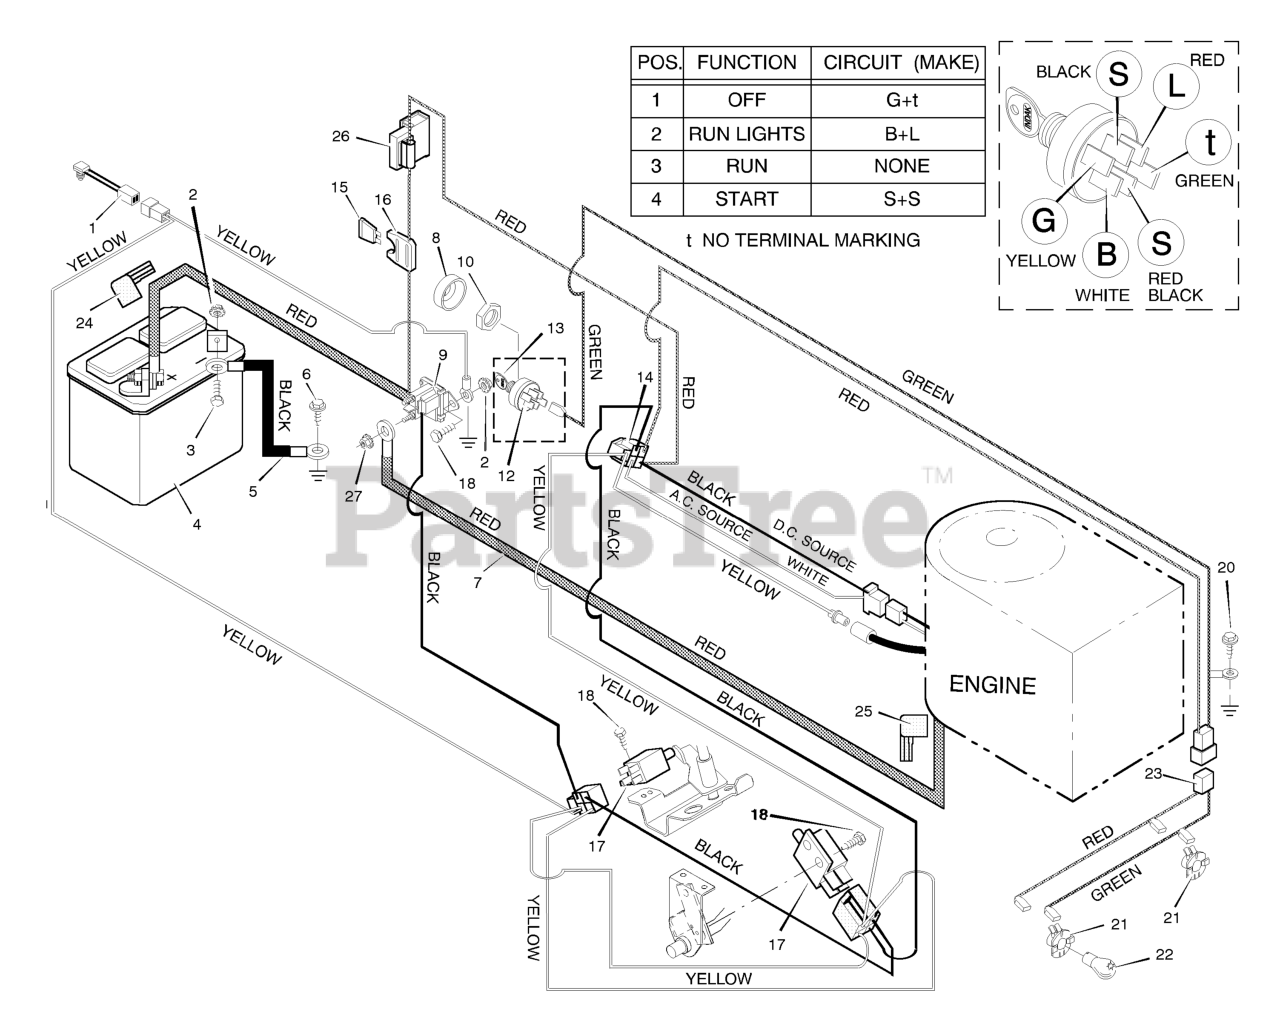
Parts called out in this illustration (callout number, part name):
1	Switch, Seat Sensor
2	Locknut
3	Bolt, Hex
4	Battery
5	Cable, Battery Ground
7	Cable, Red Battery
8	Cap, Ignition
9	Solenoid
10	Nut
12	Switch, Ignition
13	Key, Ignition
14	Harness, Chassis Wire
16	Holder, Fuse
17	Switch, Clutch
20	Screw
21	Socket, Light
22	Bulb, Light
23	Harness, Light Wire
24	Cover, Terminal
25	Cover,
26	Ammeter
27	Locknut
